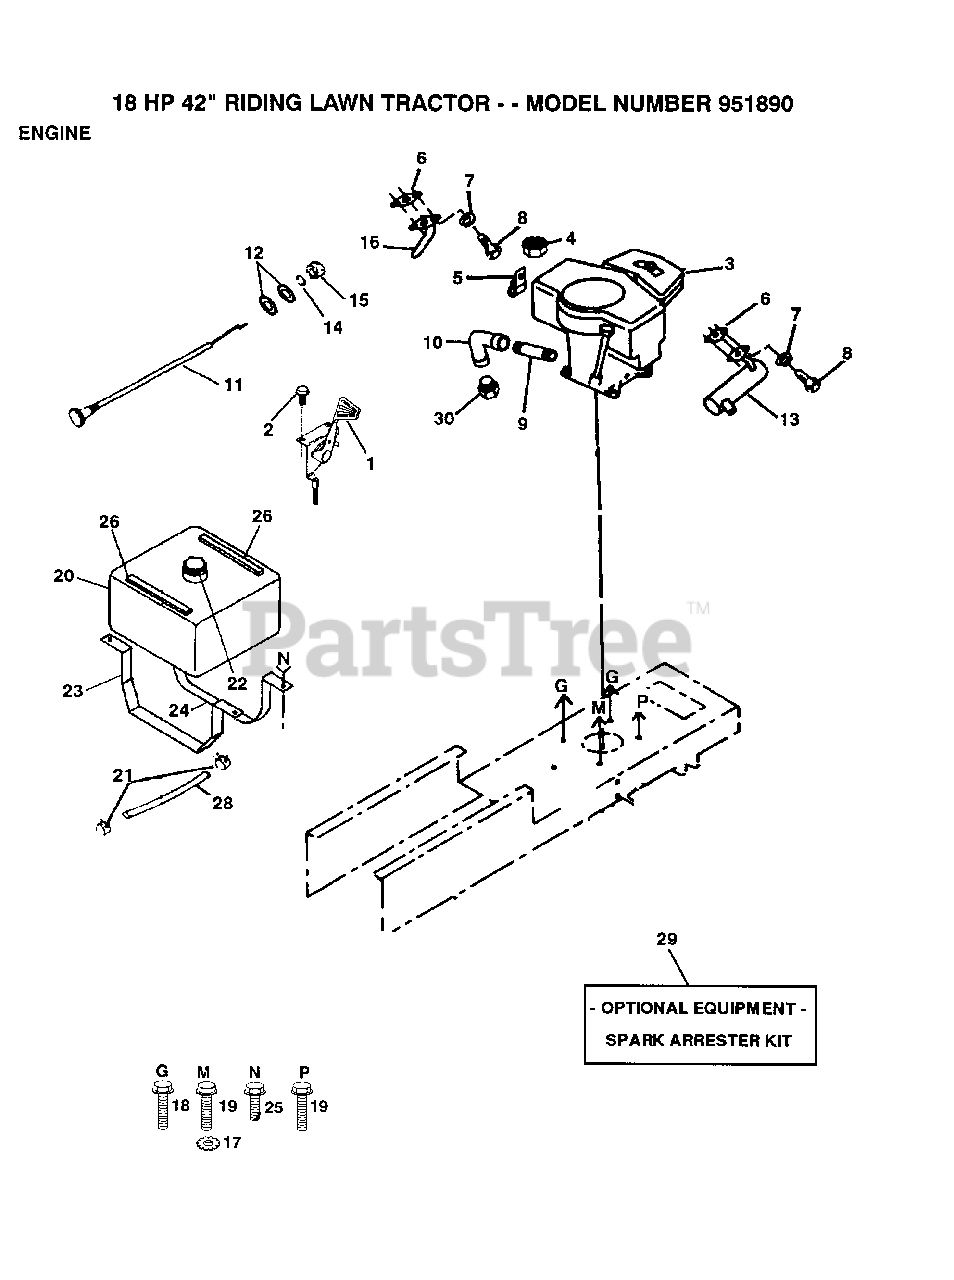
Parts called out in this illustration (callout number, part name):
2	SCREW LT
4	NUT
5	CLIP T
7	LOCKWASHER
9	PIPE NIPPLE LT
10	ELBOW
11	CHOKE CONTROL
12	WASHER
14	LOCKWASHER
16	EXHAUST TUBE T
17	LOCKWASHER
18	SCREW LT
19	SCREW LT
21	HOSE CLAMP
23	"STRAP,TANK"
24	"STRAP,TANK "
25	SCREW LT
26	"STRIP,FORM"
28	HOSE T
